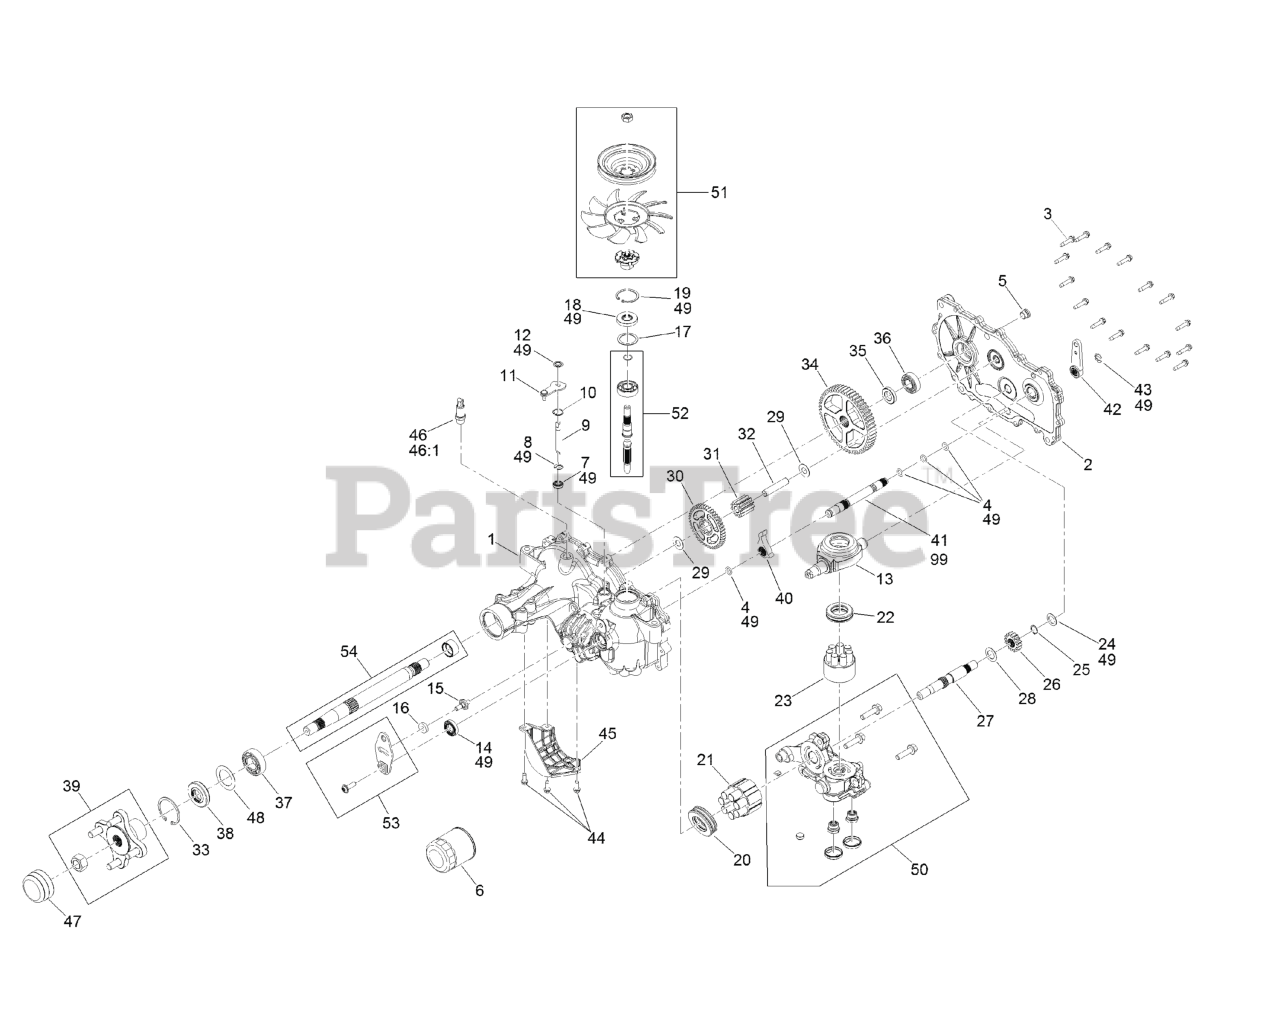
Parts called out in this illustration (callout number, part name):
1	MAIN HOUSING KIT
2	RH SIDE COVER KIT
3	SCREW-HHF
5	PLUG-THREAD, STRAIGHT
6	ELEMENT-OIL FILTER, HYD
7	SEAL-LIP
8	RING-RETAINING, EXTERNAL
9	ROD-BYPASS
10	RING-RETAINING, INTERNAL
12	RING-RETAINING, EXTERNAL
13	SWASHPLATE-TRUNNION
14	SEAL-LIP
16	PUCK-FRICTION
18	SEAL-LIP
19	RING-RETAINING
20	BEARING-THRUST
21	MOTOR CYLINDER BLOCK KIT
22	BEARING-THRUST
23	PUMP BLOCK ASM
24	WASHER-FLAT
25	RING-RETAINING
26	GEAR-16T
27	SHAFT-MOTOR
30	GEAR-43T
31	GEAR-11T
32	PIN-JACKSHAFT
33	RING-RETAINING
34	GEAR-54T
36	BEARING-BALL
37	BEARING-BALL
39	HUB KIT
40	PAWL-BRAKE
41	SHAFT-BRAKE, INBOARD
42	HANDLE-BRAKE
43	RING-RETAINING, EXT
45	GUARD-FILTER, RH
46	ADAPTER-STRAIGHT
46:1	O-RING
47	COVER-NUT, AXLE
49	SEAL KIT
50	RH CENTER SECTION KIT
51	FAN PULLEY KIT
52	INPUT SHAFT KIT
53	CONTROL ARM KIT
54	AXLE SHAFT KIT
99	BRAKE SHAFT SEAL KIT
